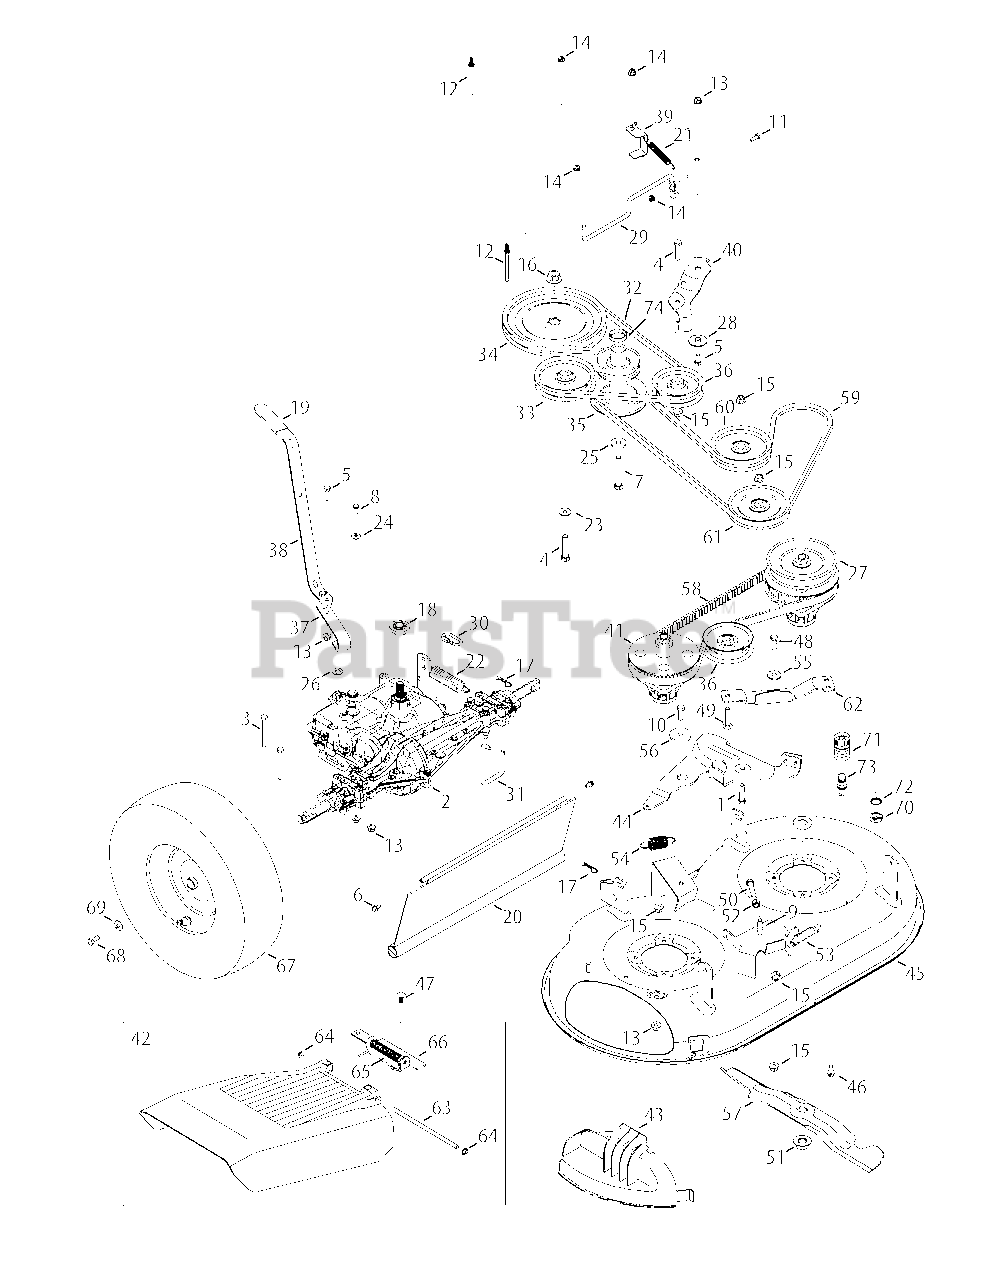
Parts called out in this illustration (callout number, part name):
1	Hex Head Cap Screw, 3/8-16 x 1.75
2	Transaxle, 4 Speed Drive Assembly
3	Hex Head Cap Screw, 5/16-18 x 2.75
4	Hex Head Cap Screw, 3/8-16 x 1.75
5	Hex Head Cap Screw, 5/16-18 x 1.00
6	Screw, 1/4-15 x 0.50
7	HHCS, 7/16-20 x 2.75 (Briggs)
7	HHCS, 7/16-20 x 3.00 (420CC)
8	Hex Head Cap Screw, 1/4-28 x .625
9	Hex Head Cap Screw, 3/8-16 x 1.50
10	Hex Head Cap Screw, 3/8-16 x 1.25
11	Hex Head Cap Screw, 1/4-20 x .75
12	Belt Keeper, .25 DIA X 3.0
13	Flangelock Nut, 5/16-18
14	Flangelock Nut, 1/4-20
15	Flangelock Nut, 3/8-16
16	Flange Nut, 9/16-18
17	Click Pin, .092 x 1.64 LG
18	Spline Pulley Hub, 5/8
19	Grip, Black
20	Trailshield, 8.35 x 19.17
21	Extension Spring, Wheel Drive
22	Extension Spring, Brake
23	Washer, Spring, .401 x .870 x .063
24	Washer, Bell, .265 x .75 x .062
25	Washer, Flat, .450 x 1.250 x .164
26	Washer, Flat, .39 x .87 x .06
27	Drive Spindle Assembly
28	Spacer, Shoulder, .5000 x .1475
29	Belt Keeper Rod
30	Coupling Link, 3/16
31	Brake Spring Mounting Rod
32	V Belt. 4L 64.2
33	Idler Pulley, 4.25 DIA
34	Flat Sheave, DIA 7.75
35	Engine Pulley, 3.20 x 4.35 DIA
36	Idler Pulley, 3.50 DIA
41	Spacer Spindle Assembly
42	Chute Deflector Assembly
43	Mulch Cover
44	Idler Arm Assembly
46	Screw, 5/16-18 x .750
47	Bolt, Carriage, 5/16-18 x .750
48	Hex Head Cap Screw, 3/8-16 x 1.00
49	Screw, Carriage, 3/8-16 x 1.75
50	Hex Head Cap Screw, 3/8-16 x 2.00
51	Flange Nut, 5/8-18
52	Hex Nut, 3/8-16
53	Extension Spring, Timing Belt
54	Extension Spring, Deck Brake
55	Shoulder Spacer, .625 ID x .169
56	Shoulder Spacer, .8840 x .190
57	Blade 2 in 1
58	Timing Belt, .315 x .787
59	V Belt, 72.2", Aramid
60	Idler Pulley, 4.25" DIA
61	Idler Pulley, V-Type, 5.0 DIA
62	Timing Idler Bracket
63	Deflector Pin
64	Push Cap
65	Deflector Torsion Spring
66	Deflector Hinge Bracket
67	Wheel, 16 x 4 x 8
68	Hex Screw, 5/16-24 x .750
69	Washer, Bell, .340 x .872 x .060
70	Nut, Hex, M16-1.5
71	Water Nozzle Adaptor
72	Washer, Lock, 5/8
73	Deck Water Nozzle
74	Spacer, 1.0 x 1.28 x .31 (420CC)
